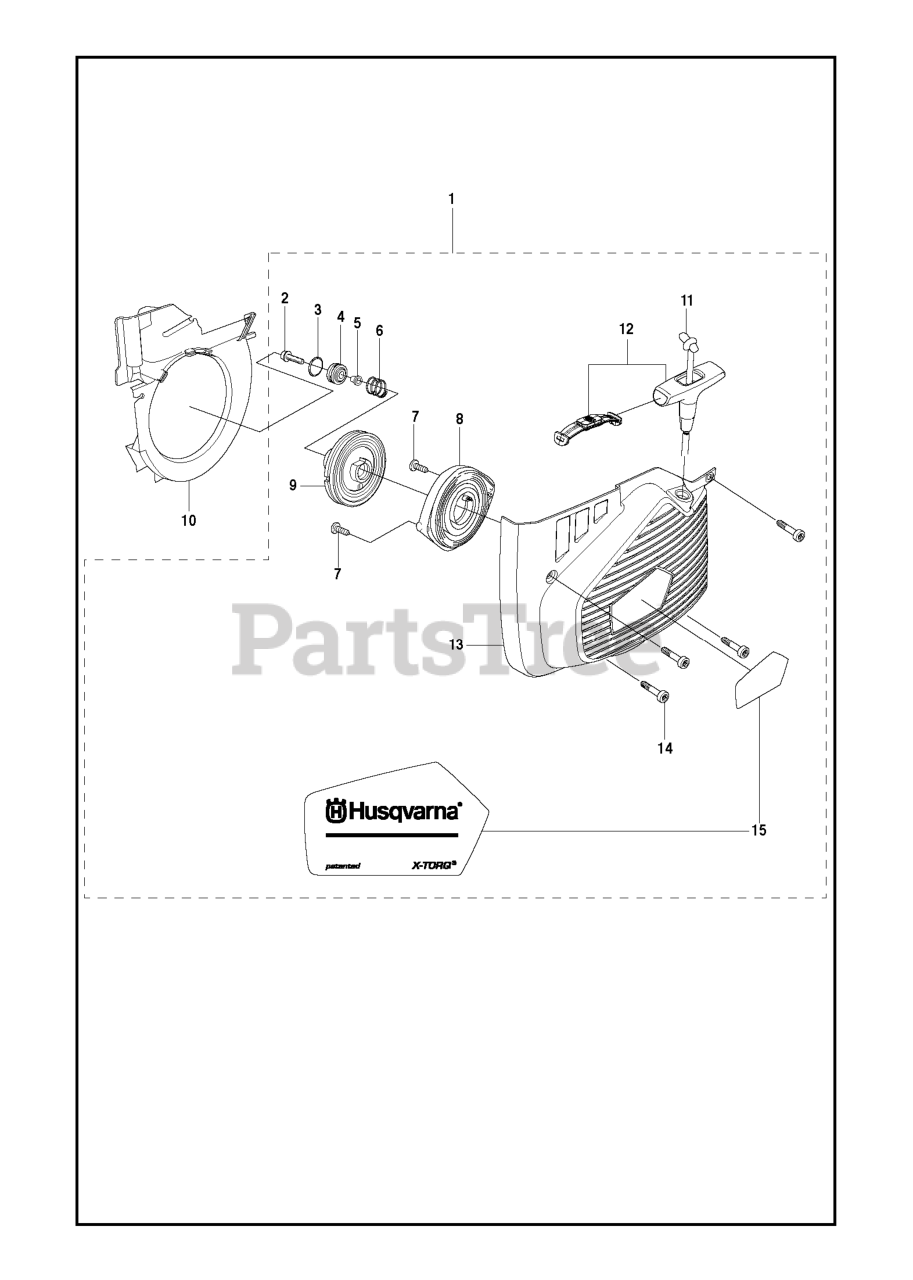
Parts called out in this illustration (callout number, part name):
1	STARTER ASSY
2	SCREW
4	RP WASHER
7	SCREW CITXPANT
8	RETURN SPRING
9	STARTER PULLEY
10	COOLING AIR CONDUCTOR
11	STARTER ROPE 50 M
11	STARTER ROPE
12	STARTER HANDLE ASSY
13	STARTER COVER K970II
14	SCREW ITXSCM
15	DECAL STARTER K760 / K970
